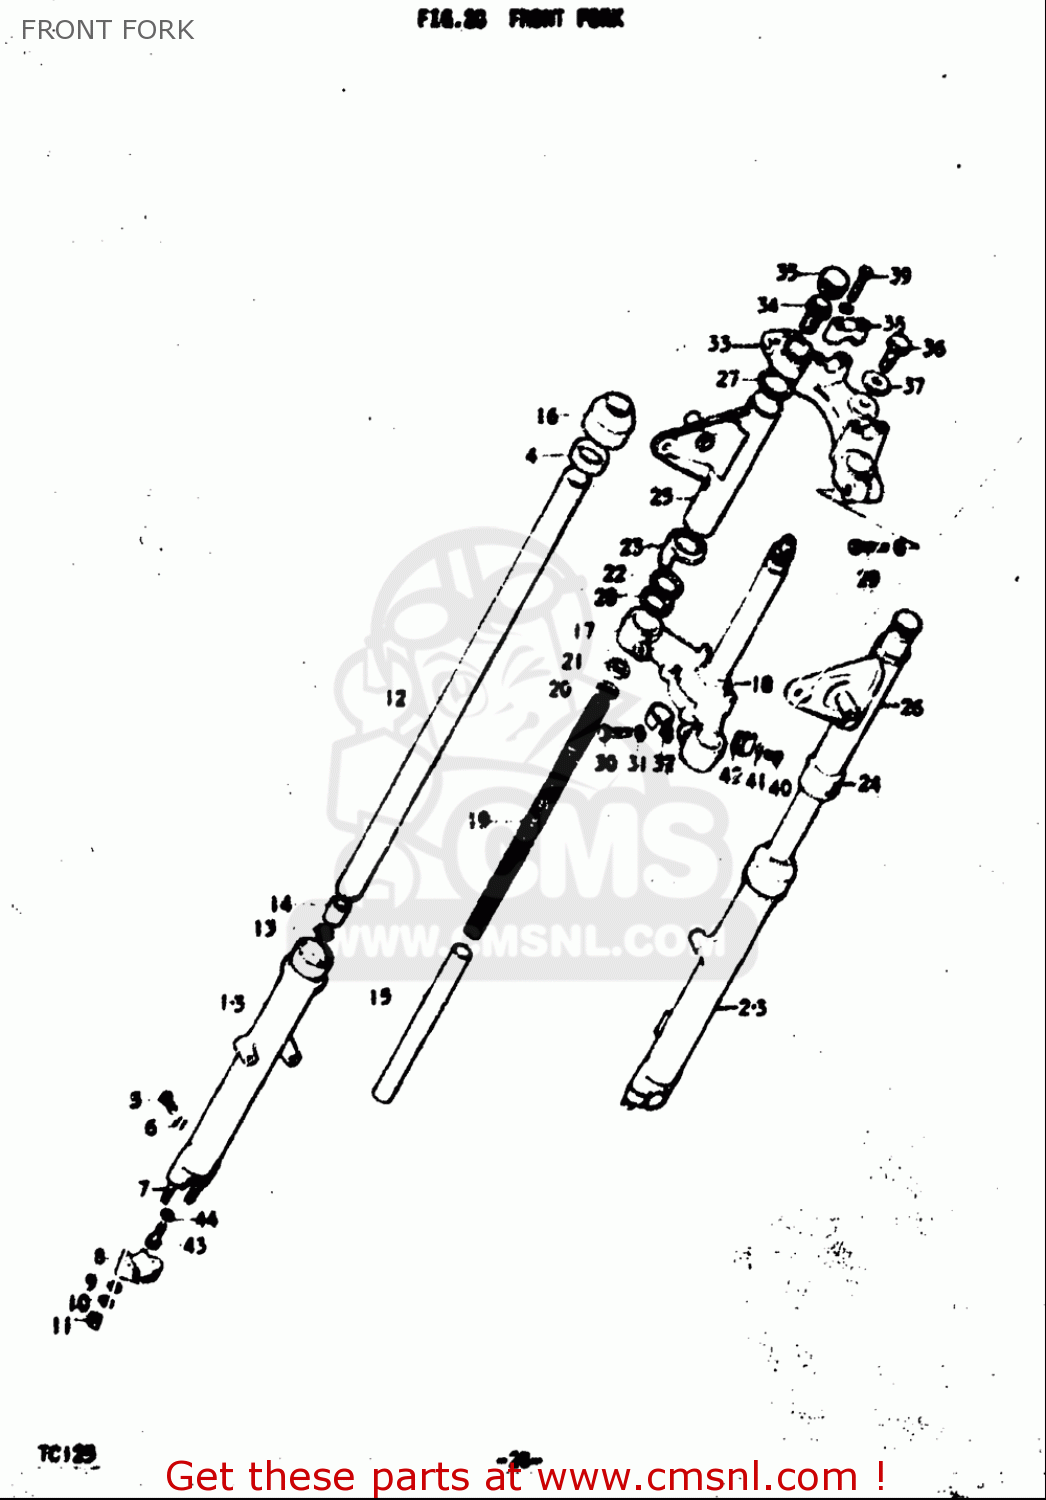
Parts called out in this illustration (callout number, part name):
4	SEAL,OIL
5	SCREW
6	GASKET,DRAIN,PLUG (NAS)
7	BOLT,STUD
9	WASHER
10	WASHER,LOCK
11	NUT
14	PISTON
16	SEAL,DUST
18	RACE,STEERING OUTER LWR
20	GUIDE,SPRING
21	SEAT,SPRING
22	CUSHION,HEAD LAMP BRACKET
23	CUSHION,HEADLAMP BRACKET
25	BRACKET,HEADLAMP HOUSING
26	BRACKET,HEADLAMP,LEFT
27	SEAT,HEADLAMP BRACKET
29	BOLT
31	WASHER,LOCK
34	CAP
36	BOLT,FR FORK(10X33)
37	WASHER
39	BOLT
40	SCREW
41	WASHER,LOCK
42	CLIP
44	GASKET (NAS)
